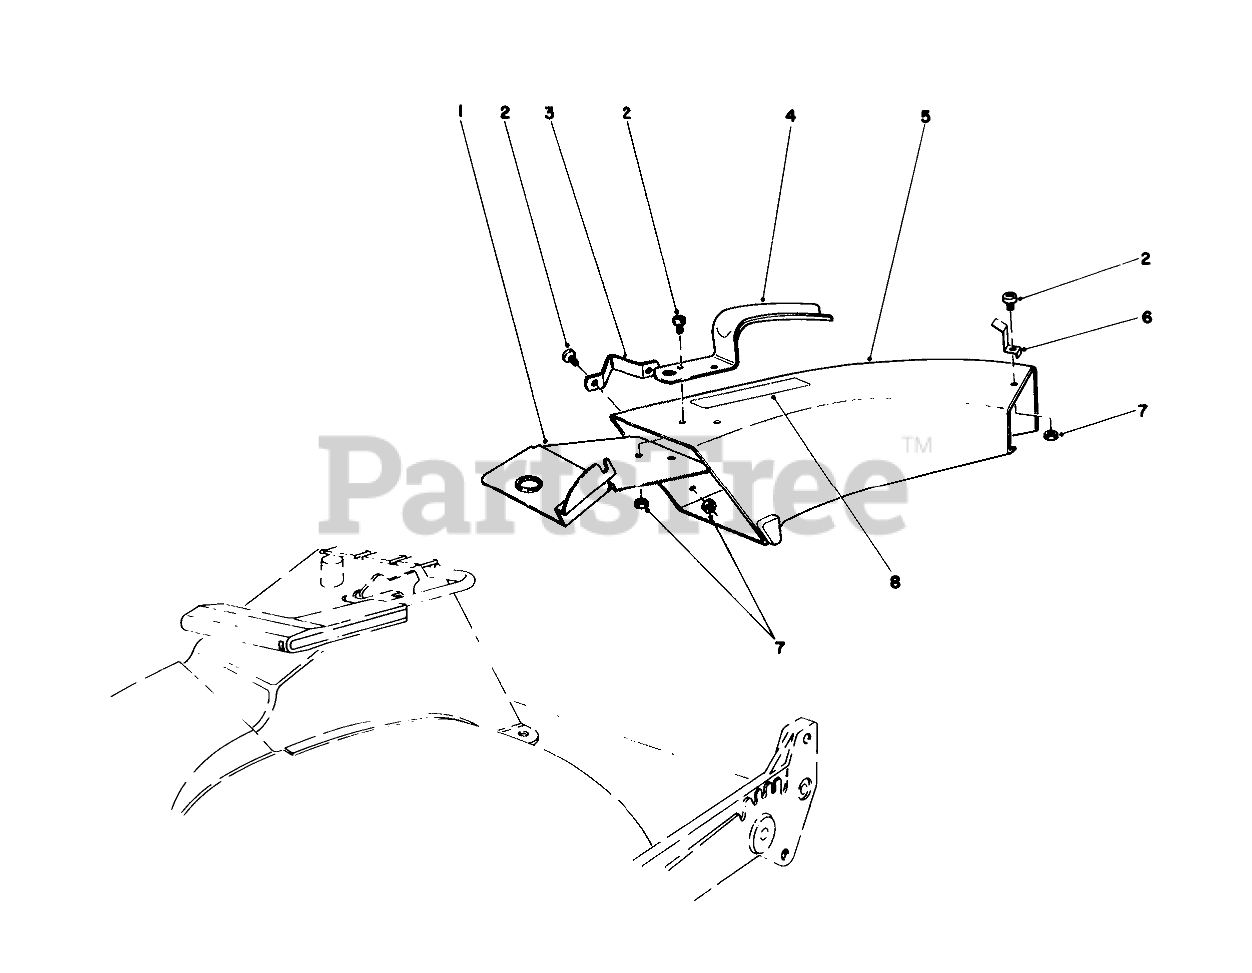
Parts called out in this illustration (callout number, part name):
1	Plate-Discharge Chut
2	10-24 X 5/8 PAN HD MS
3	SIDE BRACKET
4	CHUTE HANDLE
5	Chute-Discharge (Incl. Ref. #8)
7	NUT-LOCK, NI
8	DECAL CAUTION
